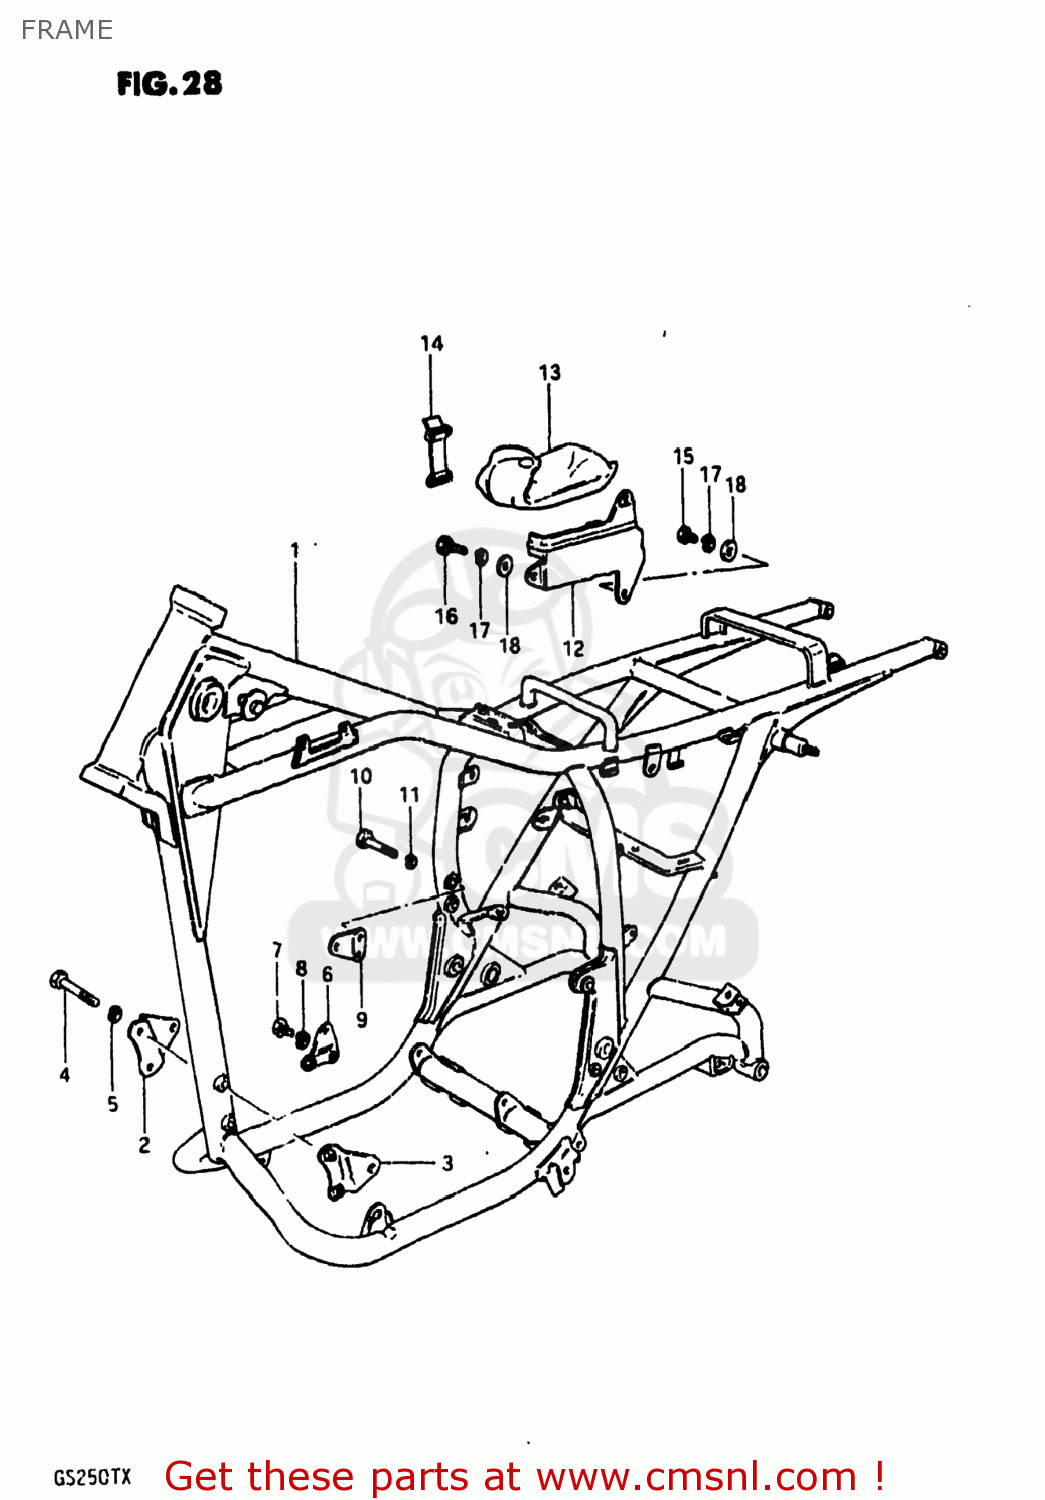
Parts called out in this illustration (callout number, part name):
1	FRAME
2	PLATE,ENGINE MOUNTING
3	PLATE,ENGINE MOUNTING
4	BOLT
5	LOCK WASHER
6	PLATE,ENGINE MOUNTING
7	BOLT
8	LOCK WASHER
9	PLATE,ENGINE MOUNTING
10	BOLT 8X45
11	LOCK WASHER
12	HOLDER,TOOL
13	TOOL ASSY
14	BAND
15	SCREW 6X12
16	SCREW
17	LOCK WASHER
18	WASHER
